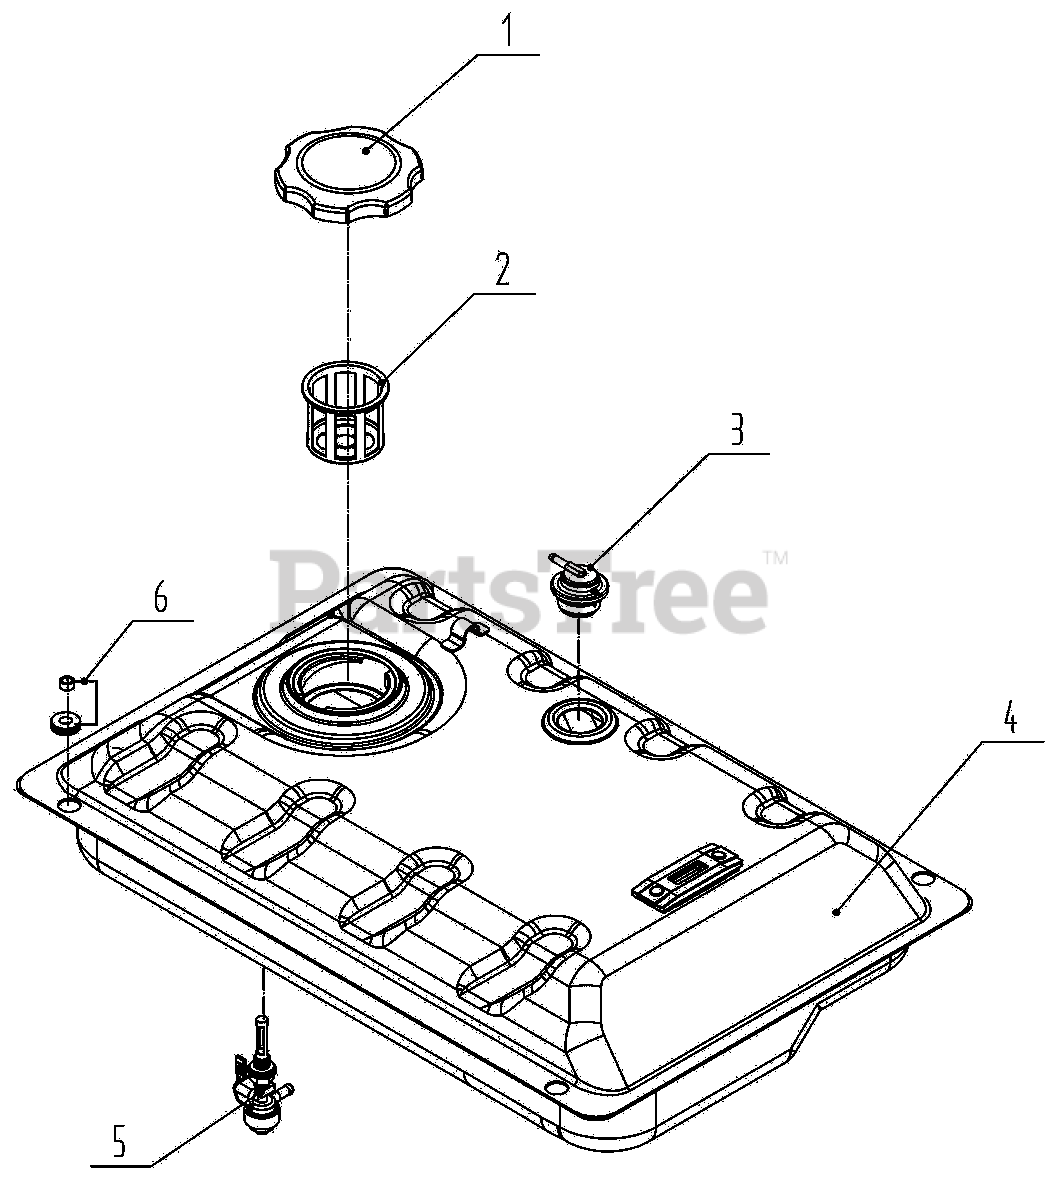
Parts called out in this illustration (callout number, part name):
1	FUEL TANK CAP
2	FUEL TANK FILTER
3	ROV
4	WELDMENT, FUEL TANK
5	FUEL SWITCH
6	FUEL TANK SHOCK ABSORPTION
